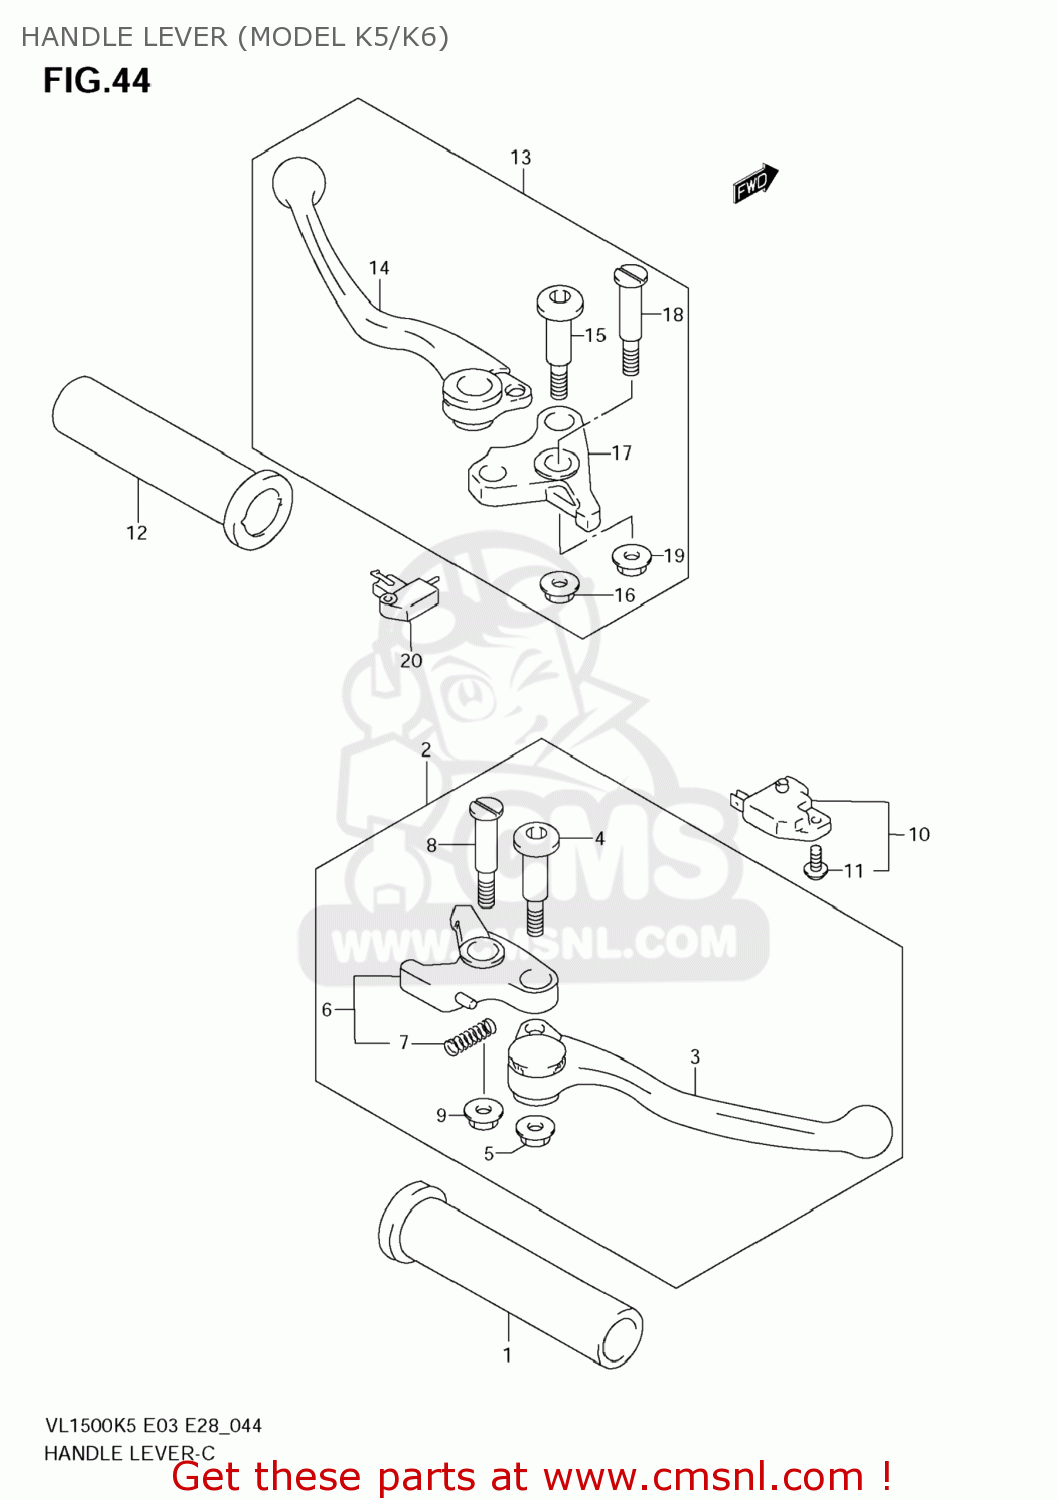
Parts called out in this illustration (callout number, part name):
1	GRIP,THROTTLE
2	LEVER ASSY,BRAKE
3	LEVER,ADJUST
4	BOLT,LEVER
5	NUT
6	KNOCKER
7	SPRING
8	BOLT,LEVER PIVOT
9	NUT
10	SWITCH ASSY,ST
11	SCREW
12	GRIP,L
13	LEVER ASSY,CLUTCH
14	LEVER ASSY,CLUTCH
15	BOLT,LEVER
16	NUT
17	KNOCKER
18	BOLT,LEVER PIVOT
19	NUT
20	SWITCH ASSY,CLUTCH
